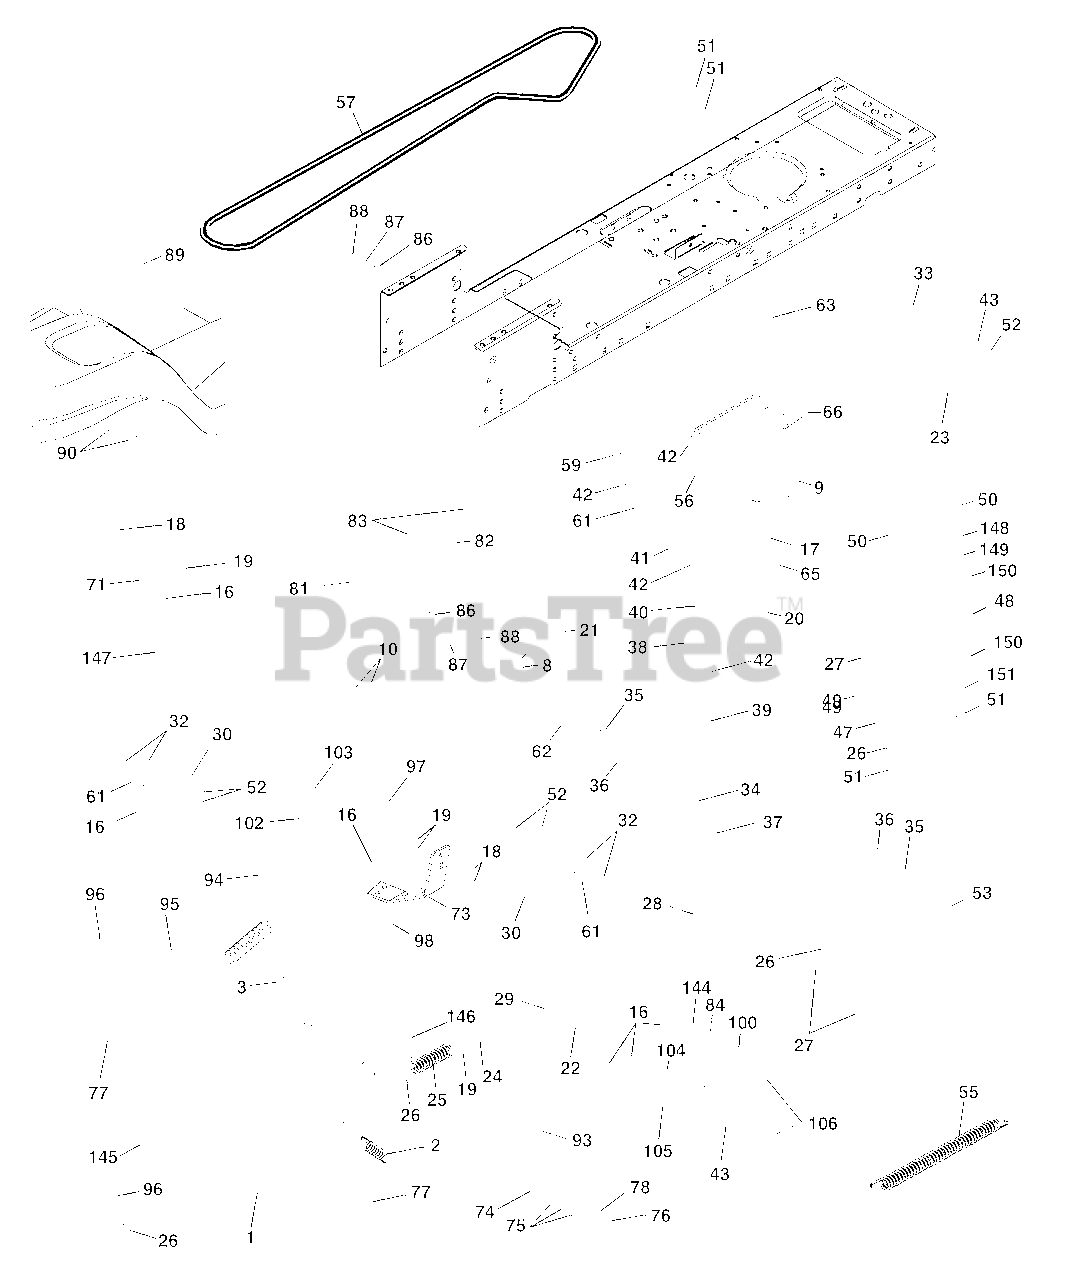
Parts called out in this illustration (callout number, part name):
1	Transaxle w/cas Hydro 310-0650
2	Spring, Return, Brake
3	Pulley, Transaxle Hydro 750 LT
8	Rod Shift STLT
9	Clutch Electric
10	Pin Cotter 1/8 x 1 CAD
15	Bolt Hex 5/16-18 Unc Flghd
16	Nut Lock Hex W/Ins. 5/16-18 Unc P
17	Washer 1-1/2 OD x 15/32 ID x .250
18	Bolt Fin Hex 3/8-16 Unc x 1 Gr.5
19	Nut Lock Hex W/Ins 3/8-16 Unc
20	Bolt, Hex 7/16-20 x 4-1/4 Ga. 5
21	Knob Deluxe 1/2-13 UNC BLK/BLK
22	Rod, Brake Hydro
23	Bracket Asm Mtg CL
24	Nut Hex Jam 3/8-16 UNC
25	Spring, Brake Rod
26	Washer
27	Pin Cotter 1/8 x 3/4 CAD.
28	Rod, Parking Brake
29	Cap,Parking Brake
30	Bracket, Transaxle
32	Bolt Hex Hd 5/16-18 Unc x 3/4
33	Bolt Carriage 5/16-18 UNC x 3/4
34	Shaft, Foot Pedal
35	Bearing, Nylon
37	Pin, Roll
38	Pulley, Idler, Flat
40	Spacer Split
41	Keeper, Belt Idler
42	Washer 13/32 x 13/16 x 12 Ga
43	Washer 11/32 x 5/8 x 12 Ga.
47	Pulley, Idler, V-Groove Plastic
48	Bellcrank Clutch Grnd Drv STL
49	Retainer, Belt Style Spring
50	Bolt
52	Nut Crown Lock 5/16-18
53	Link, Clutch
55	Spring, Return, Clutch
56	Bolt, Fin Hex 3/8-16 UNC x 1 1/4
57	V-Belt, Ground Drive
59	Keeper, Center Span
61	Screw Thdrol. 3/8-16 x 3/4 Ty. TT
62	Cover, Pedal Premium
63	Pulley, Engine
65	Washer Lock Hvy HLCL Spr 7/16
66	Keeper Belt Engine
71	Strap Torque Lh Hydro 18/20" T
73	Strap Torque Rh Hydro 0650
74	Spacer, Split
75	Washer 25/32 x 1-1/4 x 16 Ga.
77	Key, Square
78	Washer 25/32 x 1-5/8 x 16 Ga
81	Shaft Asm. Cross Hydro 20" Tires
82	Spring Torsion T/A
83	Washer 17/32 x 3/4 x 16 Ga.
84	Rod, Tie Hydro 20" Tires SPH Ball 4.75
86	Bushing Rod Strig. 629/632 ID
87	Washer 21/32 x 1-1/4 x 16 Ga.
88	Ring Klip #5304-62
89	Console, Hydro STLT Fender
90	Nut Self-Thd Wsh-Hd 1/4 Zinc
91	Bolt Fin Hex 5/16-18 x 2-1/4
92	Bolt Fin Hex 5/16-18 Unc x 1-1/2
93	Line Fuel Hydro 4"
94	Fan, Hydro 7"
95	Control Asm. Bypass Hydro
96	Retainer Spring 1" Zinc/Cad
97	Keeper Belt Rh Hydro 0750.18/20"
98	Nut Keps Hex 3/8-16 Unc
100	Washer 11/32 x 3/4 x 16 Ga.
102	Washer Belleville .501D x 1.50D
103	Nut Hex Jam Toplock 1/4-20 Unf
104	Arm, Control Hydro
105	Screw Cap Hex 5/16 x 18 x 1
106	Bolt Fin Hex 5/16-18 Unc x 1-1/4
149	Spacer Retainer PM Mower
150	Bushing Nylon Collered
151	Washer 13/32 x 2 x 10 Ga.
